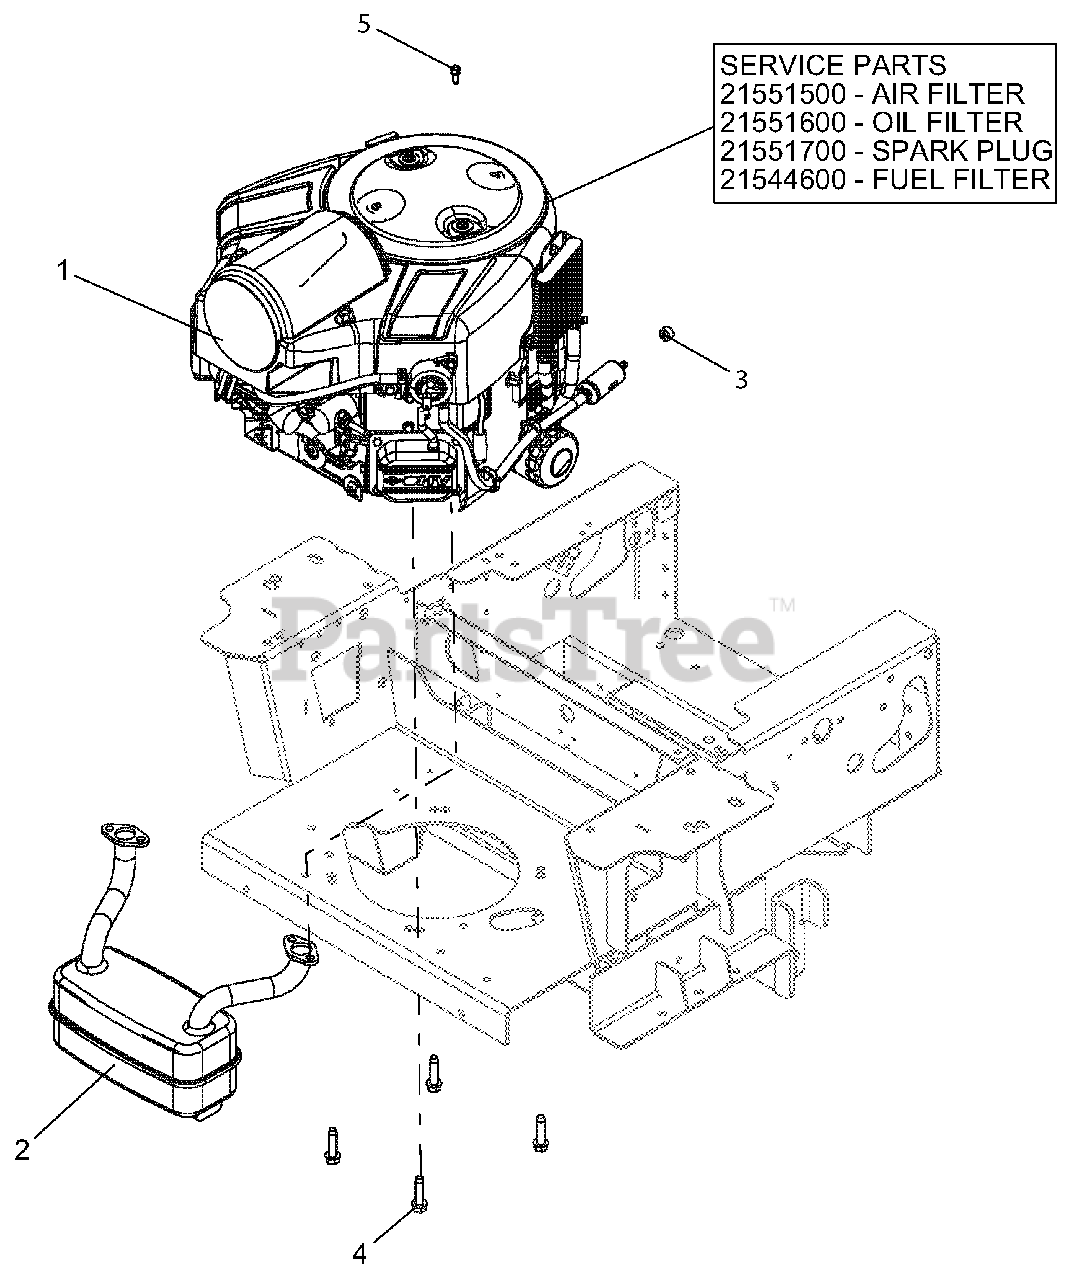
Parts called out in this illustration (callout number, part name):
1	ENGINE, BRIGGS 724CC VERT SHAFT
1	AIR FILTER
1	OIL FILTER
1	SPARK PLUG
1	FUEL FILTER
2	ASM, MUFFLER
3	CLAMP, FUEL LINE
4	SCR-TAP .38-16X1.50 HWH TR YZ
5	SCR-TAP .25-20X.62 HWH TR YWZ
